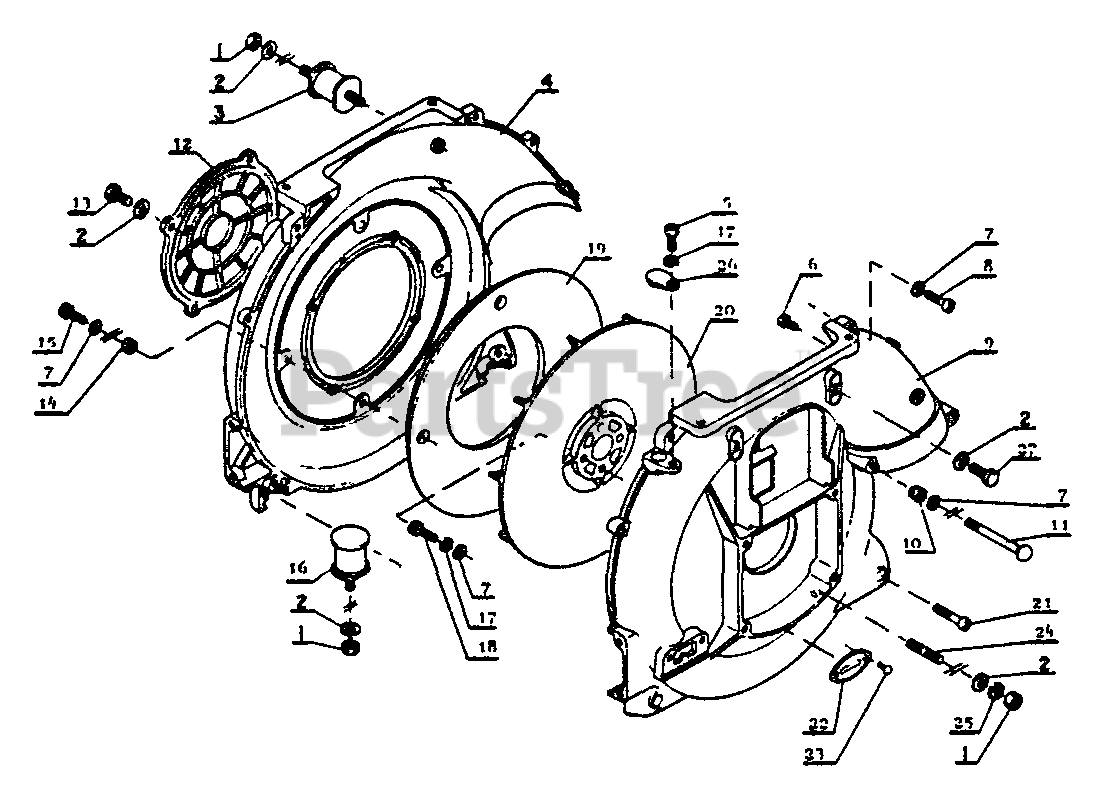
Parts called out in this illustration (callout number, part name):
1	NUT, HEX M6
2	WASHER 6.5×11.5×0.8
4	COVER, FAN - INNER
5	SCREW 5×10
6	SCREW 4×8
7	WASHER, FLAT 5.5×10×0.8
8	SCREW 5×20
9	COVER, FAN - OUTER
10	NUT - 5
12	SHIELD, DEBRIS
13	BOLT 6×10
15	BOLT 5×12
17	WASHER, SPRING 5
18	BOLT - 5×16
19	SEPARATER
21	SCREW 5×25
22	MODEL PLATE
23	RIVET
24	STUD
25	WASHER, SPRING 6
26	PLUG
27	BOLT - 6×14
